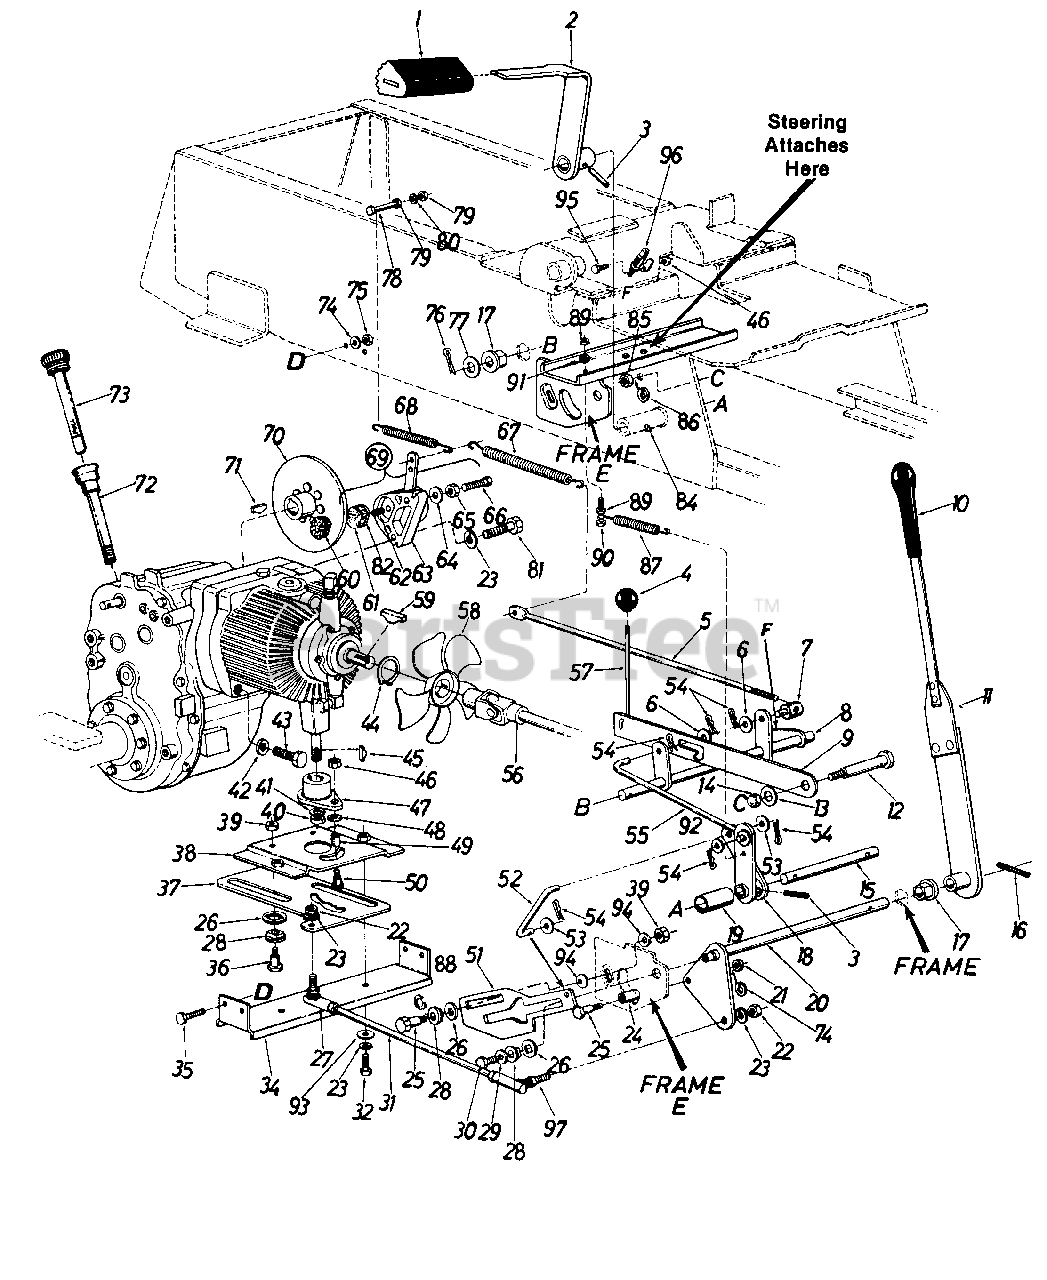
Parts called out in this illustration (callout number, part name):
1	Foot Pad
4	Ball Knob Brake
5	Brake Rod
6	Fl-Wash. .375" I.D. x 1.00" O.D. x .030
7	Ferrule
8	Brake Transfer Shaft Ass'y.
9	Parking Brake Cam
10	Grip
11	Control Arm Ass'y. Comp.
12	Shld Scr. .62 Dia. x 2.75" Lg.
13	Fl-Wash. .460 I.D. x 1.24 O.D. x .06
14	Push Speed Nut for .625 Dia. Shaft
15	Brake Pivot Shaft
16	Spring Pin Spiral 1/4" Dia. x 1.50" Lg.*
17	Hex Flange Brg. Plastic .62 I.D.
18	Brake Hub Ass'y.
19	Spacer
20	Control Handle Ass'y.
21	Hex Cent. L-Nut 5/16-18 Thd.
22	Hex Nut 3/8-24 Thd.*
23	L-Wash. 3/8" Scr.*
24	Spacer
25	Shoulder Bolt
26	Fl-Wash. .63 Sq. Hole x 1.25" O.D.
27	Ball Joint Ass'y. 3/8-24 Thd. L.H.
28	Pivot Slide
29	Fl-Wash. .312 I.D. x .88 O.D.
30	Hex Ins. Scr. 5/16-18 x 1.00" Lg .
31	Tie Rod
32	Hex Scr. 3/8-16 x .75" Lg.*
34	Support Channel
35	Hex Scr. 5/16-18 x .75" Lg.*
36	Shld. Scr. .437" Dia. x .350
37	Cam Plate
38	Slide Mtg. Plate Ass'y.
39	Hex Cent. L-Nut 5/16-18 Thd.
40	Hex Nut 1/2-13 Thd.*
41	L-Wash. 1/2" Scr.*
42	Fl-Wash. .385 I.D. x .87 O.D. x .060
43	Socket Hd. Scr. 3/8-16 x 2.75" Lg.
44	Snap Ring
45	#5 Hi-Pro Key 1/8" x 5/8" Dia.
46	Hex Cent. L-Nut 1/4-20 Thd.
47	Pintle Plate Ass'y.
48	Fl-Wash. .281 I.D. x .50 O.D. x .063
49	Needle Brg. .31" I.D. x .50" O.D. x .437" Lg.
50	Shld. Scr. .31 Dia. x .500 (Socket Head)
51	Neutral Control Slide
52	Neutral Control Rod
53	Fl-Wash. .312 I.D. x .630 O.D. x .063
54	Hairpin Cotter
55	Brake Link Rod Ass'y.
56	Universal Joint Ass'y. Comp.
57	Parking Brake Link
58	Fan Ass'y.
59	#61 Hi-Pro Key 3/16 x 5/8" Dia.
60	Lining Brake
61	Lining Brake
62	Actuator Pin
63	Housing with Lever and Pin
64	Washer
66	Adjustment Pin
67	Extension Spring .59 O.D. x 6.5" Lg.
68	Extension Spring (Brake Return)
69	Disc Brake Ass'y. Comp.
70	Brake Disc Ass'y.
71	Hi-Pro Key 3/16 x 3/4" Dia.
72	Dipstick Tube Ass'y.
73	Dipstick Ass'y.
74	L-Wash. 5/16" Scr.
75	Hex Nut 5/16-18 Thd.*
76	Cotter Pin 1/8" Dia. x 1.00" Lg.*
77	Fl-Wash. .635" I.D. x 1.00 O.D. x .120 Thk.
78	Hex Scr. 1/4-20 X 2.50" Lg.*
79	Hex Nut 1/4-20 Thd.*
80	L-Wash. 1/4" Scr.*
81	Hex Scr. 3/8-16 x 1.25" Lg.*
82	Backing Plate
84	Grease Fitting
85	Hex Nut 7/16-20 Thd.*
86	L-Wash. 7/16" Scr.*
87	Extension Spring
88	Wave Wash.
89	Hex Nut 1/4-20 Thd.*
90	Hex Scr. 1/4-20 x 1.25" Lg.*
91	L-Wash. 1/4" Scr.*
92	Fl-Wash.
93	Fl-Wash. .38 I.D. x 1.25 O.D.
94	Bell-Wash.
95	Hex Scr. 1/4-20 X 1/2" Lg.
96	Safety Switch (Clutch)
97	Ball Joint Ass'y. 3/8-24 Thd. R.H.
